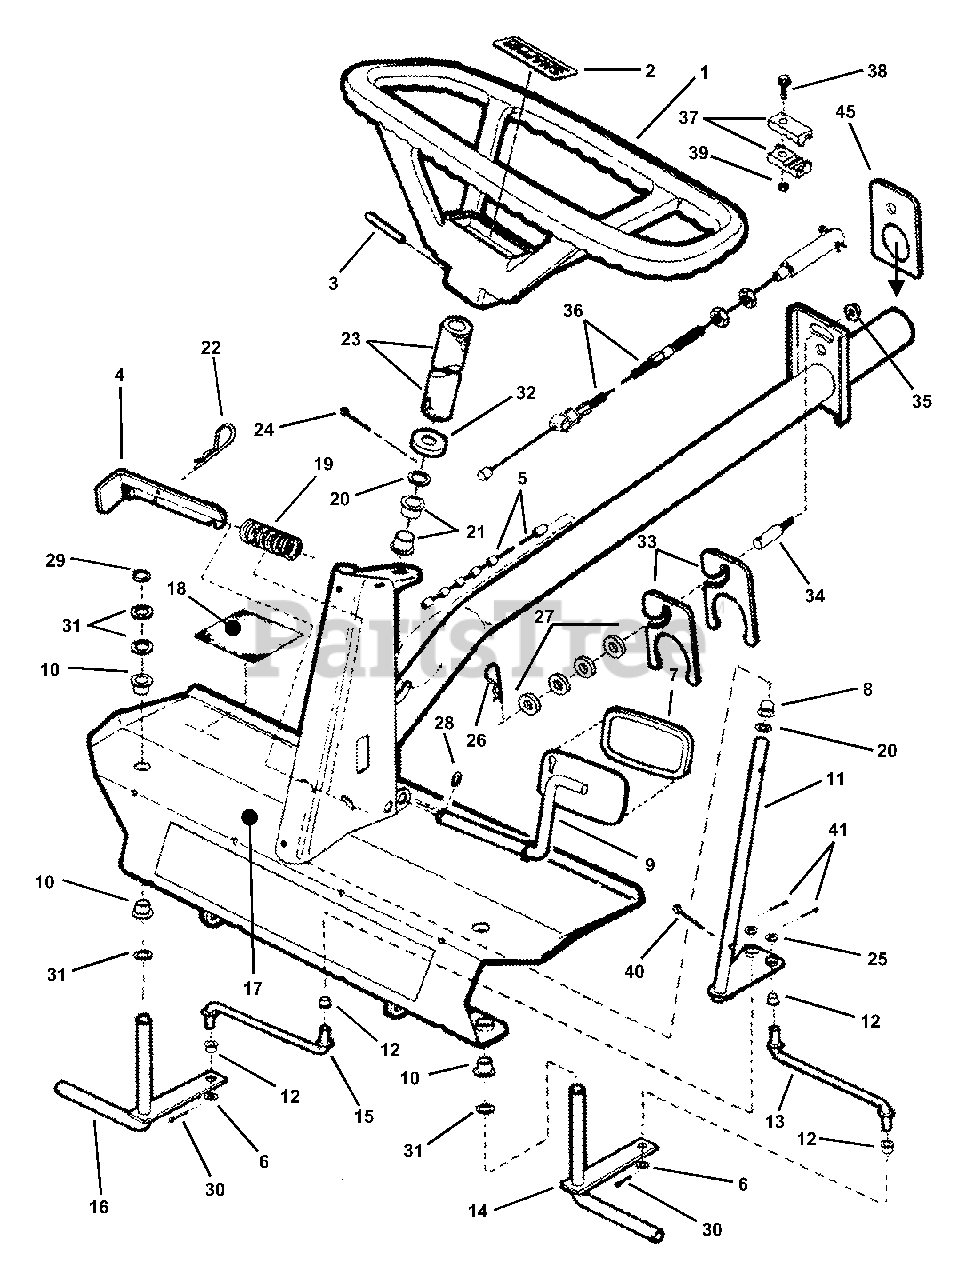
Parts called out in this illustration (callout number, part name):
1	STEERING WHEEL
2	LOGO, Steering Wheel
3	PIN, 1/4 x 1-1/2" Roll
4	LATCH, Parking Brake
5	CABLE, Clutch/Brake (54.32")
6	WASHER, 3/8" Flat
7	PAD, Clutch/Brake Pedal
8	BUSHING, Nylon
9	PEDAL, Clutch/Brake (weldment)
10	BEARING, Nylon
11	SHAFT, Steering (weldment)
12	BUSHING, Tie-Rod
13	TIE-ROD, Left Hand (7.41" long)
14	KING-PIN Weldment, Left Hand
15	TIE-ROD, R. H. (7.41" long)
16	KING-PIN, Weldment Right Hand
17	WELDMENT, Front Axle, Narrow (28" & 30" Deck)
18	FOOT PAD, Short
19	SPRING, Parking Brake
20	WASHER, 21/32 Dia.
21	BUSHING, Nylon
22	PIN, Hair
23	FOAM COVER, Steering Shaft
24	PIN, 3/16 x 1" Cotter
25	WASHER, 3/8" Flat
26	PIN, 1/8" Hair
27	SPACER, 1/2"
28	RING, 1/2" External Retaining (Heavy Duty)
29	RING, 3/4" Ext. Retaining
30	PIN, 1/8 x 3/4" Cotter
31	WASHER, 5/8 Flat
32	COVER, Steering Shaft
33	SPACER, Pivot
34	STUD, Shoulder (3/8-24 Thread)
35	NUT, 3/8-24 Hex Nyloc
36	CABLE, Brake (29" long)
37	CONNECTOR, Cable
38	SCREW, 1/4-20 x 3/4", Gr. 5
39	NUT, 1/4-20 Hex Center Lock
40	PIN, 3/16" x 1-1/2" Cotter
41	PIN, 5/32" x 1" Cotter
45	PLATE, Thrust
